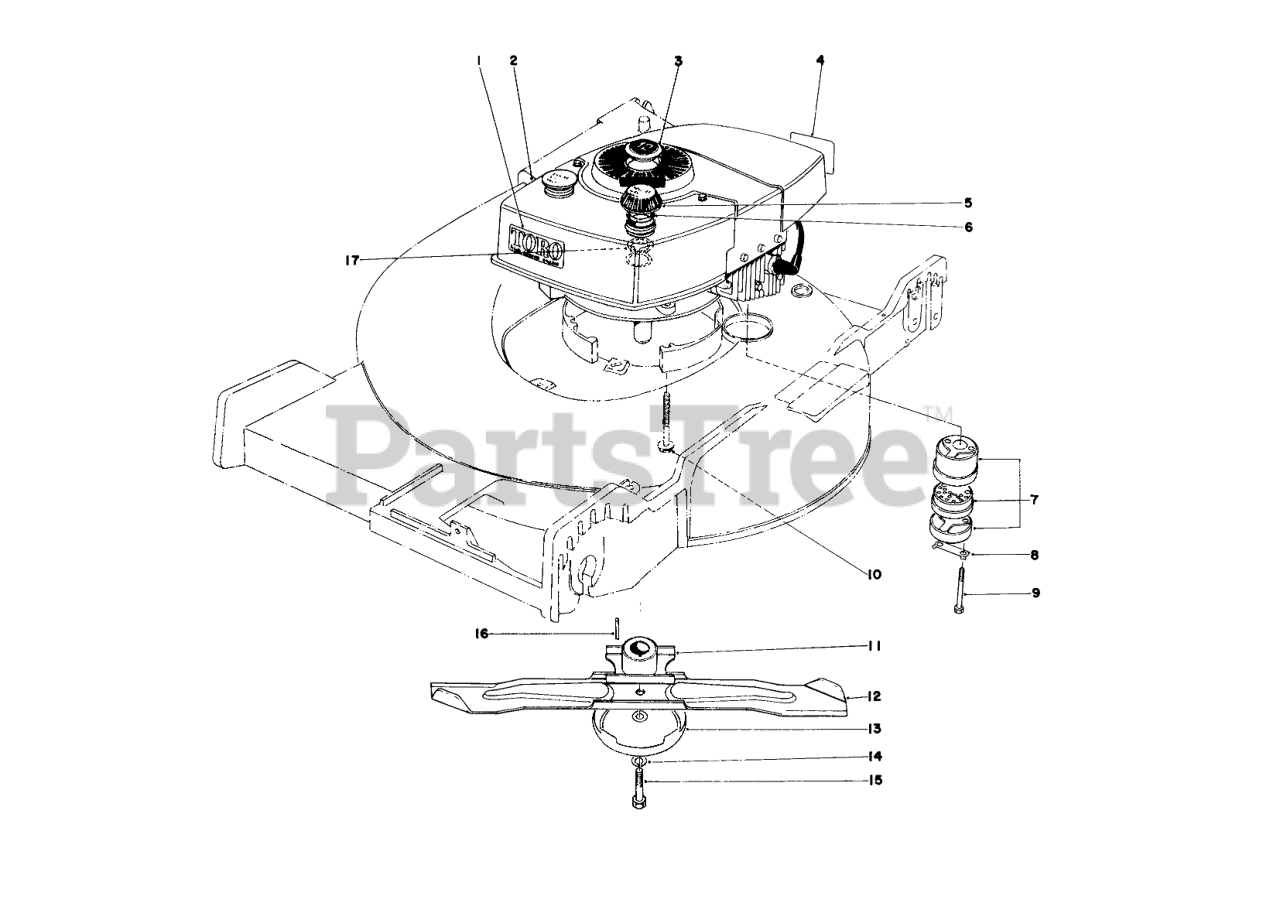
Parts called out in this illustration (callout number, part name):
1	High Torque
2	Engine
3	Plug Button
4	Decal Maintenance
5	Gas Cap (Incl. Ref. #6 & 17)
6	GASKET
7	Muffler Assembly (Incl. Ref. #8 & 9)
8	CLIP - LOCKING
9	SCREW-HH
10	3/8-16 X 2-3/4 CAPSCR
11	BLADE RETAINER WA
12	Blade
13	AntiScalp Cup
14	WASHER-LOCK
15	BLADE SCREW
17	GAS CAP BAFFLE
